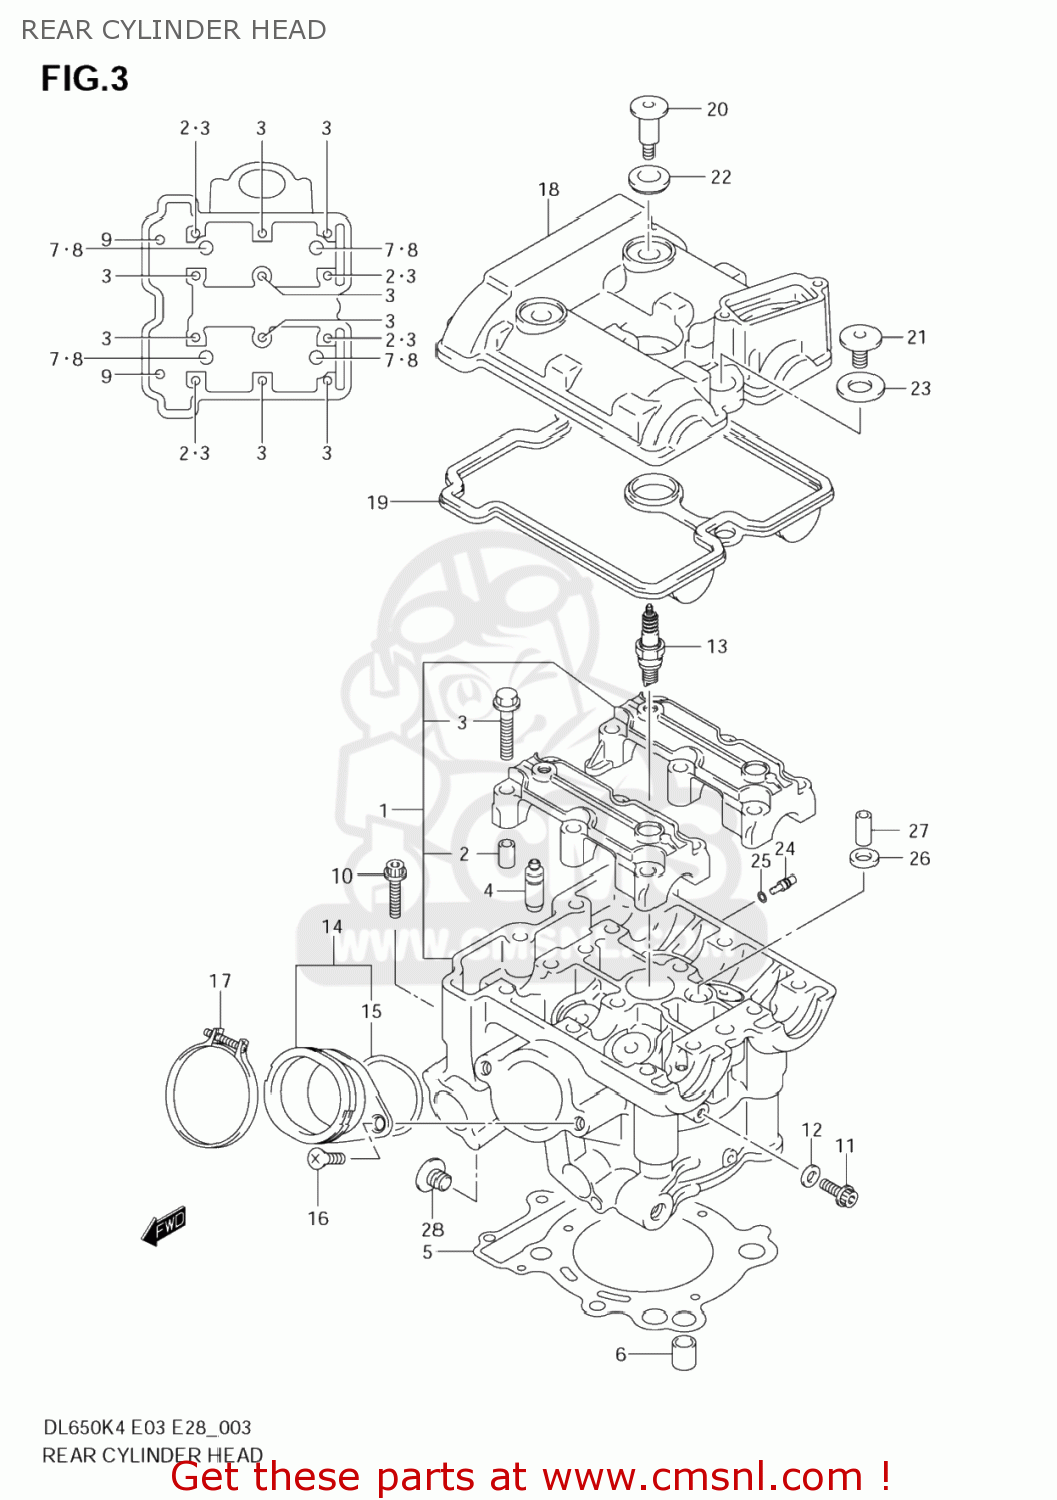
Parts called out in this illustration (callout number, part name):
1	HEAD ASSY,CYLINDER RR
2	PIN(6.2X8X11)
3	BOLT(6X39)
4	GUIDE,VALVE
5	GASKET,CYLINDER HEAD (NAS)
6	PIN
7	WASHER(10.5X19X2)
8	BOLT(10X160)
9	BOLT(6X70)
10	BOLT
11	BOLT
12	GASKET(5.8X13X1.2) (NAS)
13	PLUG,SPARK(CR8E)
14	PIPE ASSY,INTAKE RR
15	O RING(D:2.4,ID:47X42)
16	SCREW ,6X16
17	CLAMP
18	COVER,CYLINDER HEAD RR
19	GASKET,CYLINDER HEAD COVER (NAS)
20	BOLT(7X17.5)
21	BOLT(7X31)
22	WASHER(10.6X25.5X2.3)
23	CUSHION,HEAD COVER BOLT
24	JET(8)
25	O RING(D:1.2,ID:4)
26	GASKET,2ND AIR PASSAGE (NAS)
27	PIN(6.2X8X16)
28	CAP,ENGINE MOUNTING
